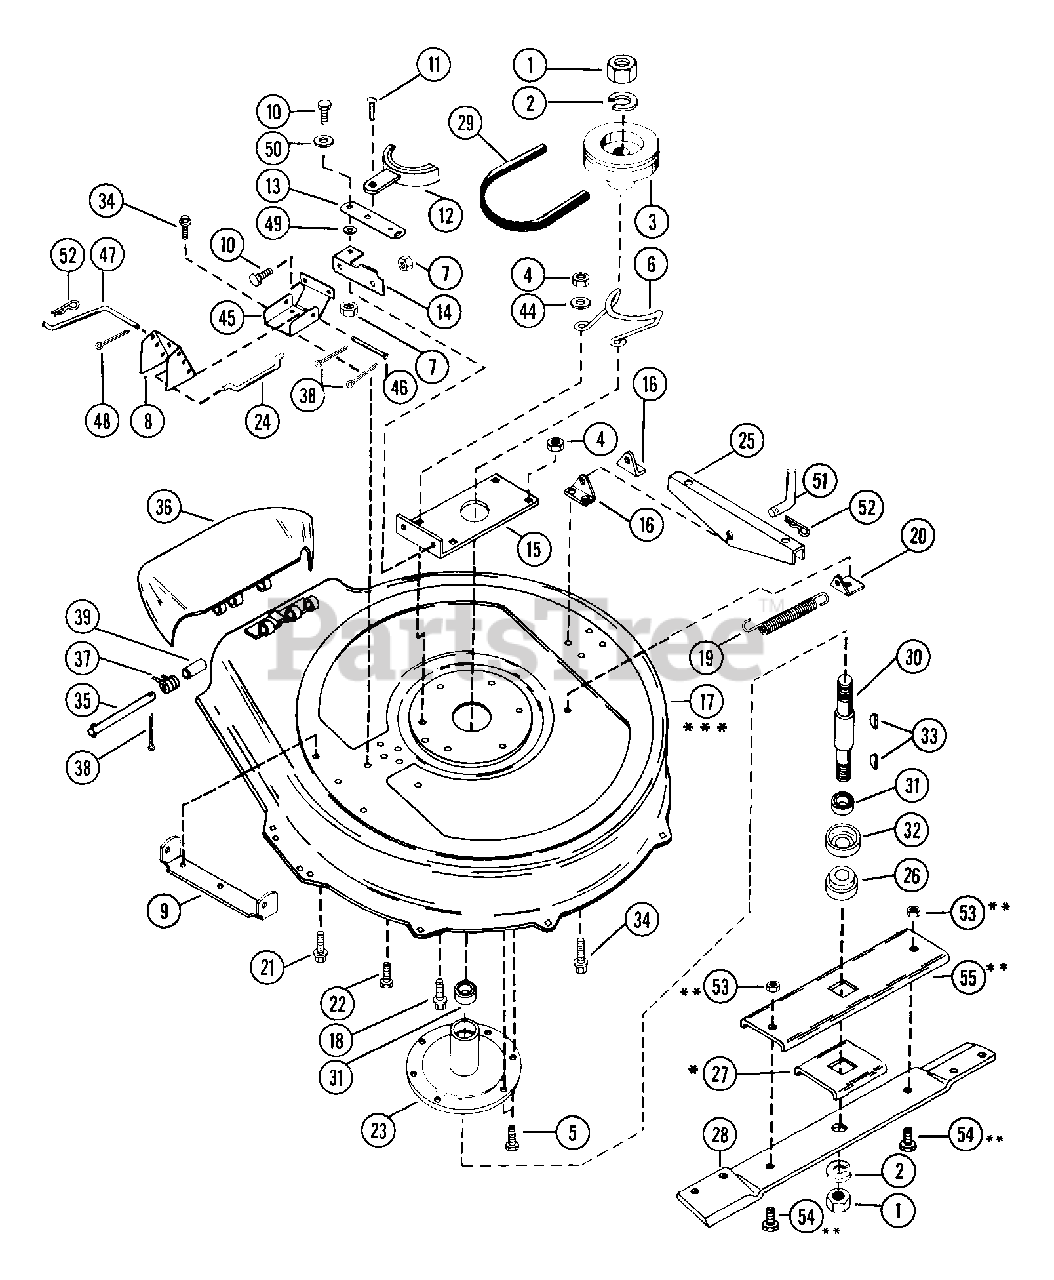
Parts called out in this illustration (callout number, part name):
1	NUT-JAM .75-10 PL
2	WSHR-LK .750X.188 MED PL
3	MOWER SHEAVE
4	NUT-LK-CTR .375-16 GR A PL
5	BLT-HEX .38-16X1.00 PL
6	MOWER BELT FINGER
7	NUT-LK .312-18 GR A PL
8	MOWER ENGAGING ARM
9	FRONT MOUNTING BRACKET
10	BLT-HEX .31-18X.63 PL GR 2
11	RVT .25X.50 RH ST
12	BLADE BRAKE
13	MOWER BRAKE LEVER
14	BRAKE BRACKET
16	REAR MOUNTING BRACKET
17	30 IN MOWER PAN
18	BLT-SERHFWH .25-20X.50 PL
19	SG-TENS .072X.51X5.31 WLD 25
20	BRAKE CLIP
21	BLT-SCRHFWH .38-16X.50 PL
22	BLT-HEX .31-18X.50 PL GR2
23	SPINDLE HOUSING
24	MOWER BRAKE LINK
25	SWIVEL BRACKET
26	RETAINER HUB
27	BLADE TRAY
28	MOWER BLADE 30 INCHES
29	V-BELT
30	SPINDLE SHAFT
31	BRG-BALL .750X1.781X.61
32	BEARING SLINGER
33	KEY-WDRF .188X.75X.313 SAE 9
34	BLT-SERHFWH .31-18X.50 PL
35	CLEVIS PIN
36	PAN CHUTE EXTENSION
37	SG-TORS .095X.50X 1.0
38	PIN-COTR .09X.75 PL
39	BSHG-SLV .334 X .502 X 1.437
44	WSHR-FL-STL .406X.865X.094 PL
45	PIVOT BRACKET
46	PIN-CLEV .309X3.50 SP
47	MOWER ENGAGEMENT LINK
48	PIN-COTR .12X.75 PL
49	SPACER BUSHING .5 X .32 X .163
50	WSHR-FL-STL .328X1.0X.094
51	CLEVIS PIN
52	PIN-HAIR INT .08X.38X1.42 YWZC
53	NUT-LK TOP .375-16 GR C YWZC
54	BLT-HEX .38-16X1.00 PL GR5
55	BLADE TRAY
